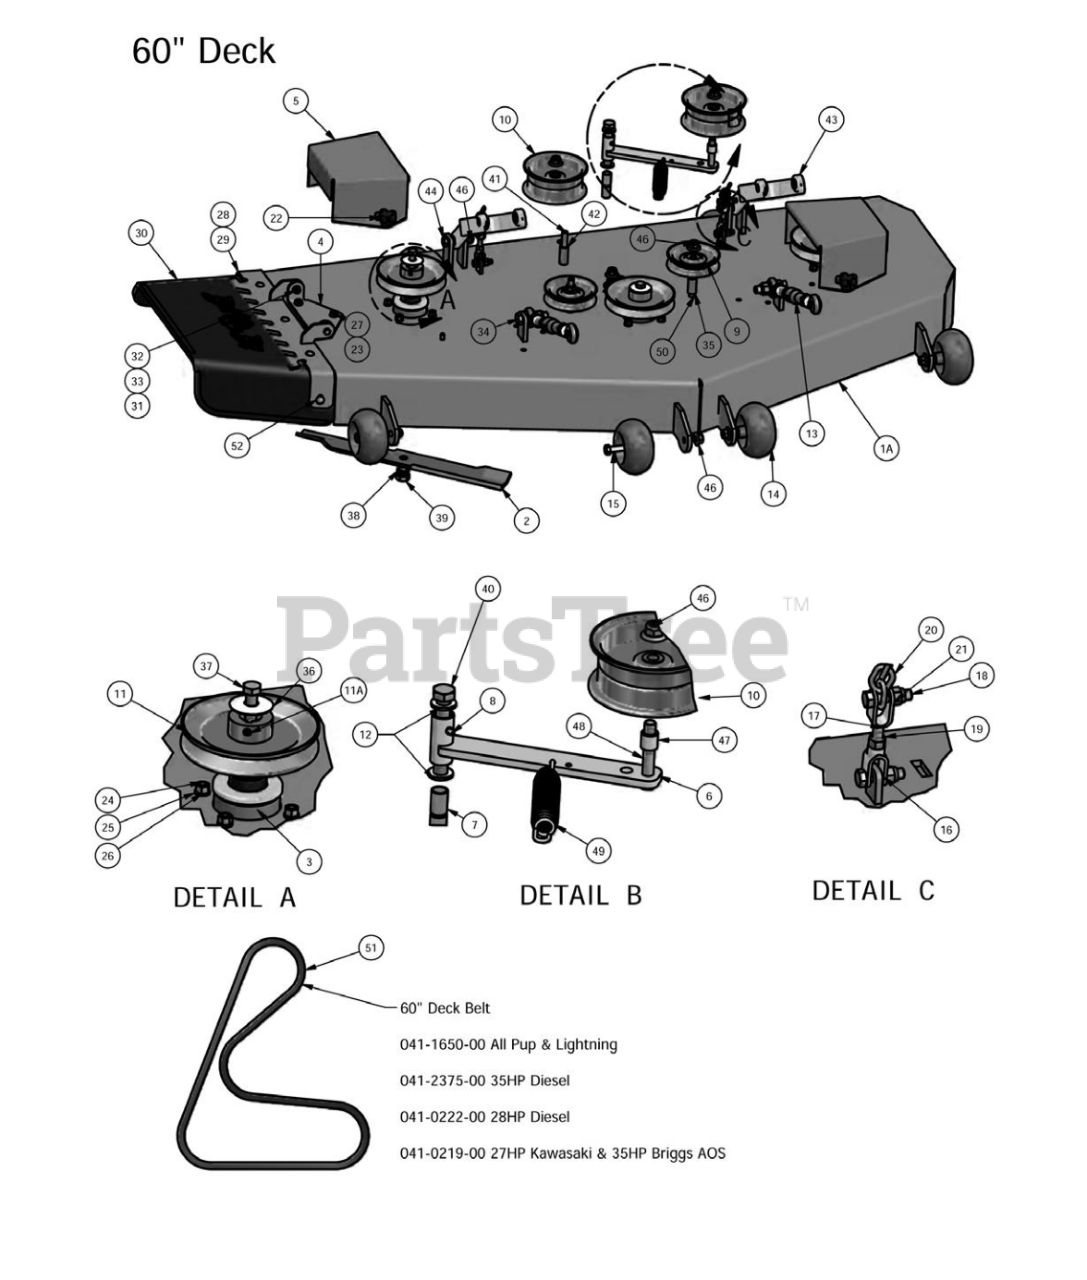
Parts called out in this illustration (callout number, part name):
1	60" Deck Complete Assembly with Spindles
1A	60" Deck Shell Only
2	60 Inch Fusion Blade
3	Double Bearing Spindle Assembly
4	Discharge Chute Hanger
5	Plastic Pulley Cover
6	Deck Idler 2009
7	5/8 x 1 1/8" Brass Bushing
8	1/4 Drive-in Grease Fitting
9	4 3/4" Idler Pulley
10	5 3/4" Deck Idler Pulley
11	6 1/4" Drive Pulley
11A	5/16" Set Screw
12	.635 ID Plastic Washer
13	Turnbuckle (Top Link)
14	Anti-Scalp Rollers
14A	Anti-Scalp Rollers Complete Assembly
15	1/2" x 4" Bolt (Grade 8)
16	Female Yoke
17A	4" Yoke & Chain Complete Assembly
17B	3" Yoke & Chain Complete Assembly
18	3/8" x 1 1/2" Hex Bolt
19	3/8" Hex Nut
20	4" Chain Assembly Lightning, AOS & Diesel
21	3/8 Nylock Nut
21A	3" Chain Assembly PUP (Only)
22	5/16" Knob
23	3/8" x 3/4" Hex Bolt
24	3/8" x 1 1/4" Hex Bolt
25	3/8" Lock Washer
26	3/8" Hex Nut
27	3/8" Flange Nut
28	60" Lower Hanger
29	60" Discharge Chute Upper Hanger Plate
30	Rubber Discharge Chute
31	.360 ID Plastic Washer
31A	Complete Assembly Rubber Discharge Chute
32	5/16" x 1" Hex Bolt
33	5/16" Nylock Flange Nut
34	5/8" x 2 1/2" Hex Bolt
35	Pup Pulley Spacer
36	Cup Washer
37	1/2" x 1 1/2" Hex Bolt
38	5/8" Lock Washer
39	5/8-18 x 1 1/2 GR 8 Hex Bolt
40	5/8" x 4" Hex Bolt
41	1/2-13 x 3 1/2 GR 5 Hex Bolt
42	1 3/4" Pulley Spacer
43	Deck Arm Assembly
44	1/2" x 2 1/2" Hex Bolt.
45	1/2" Flange Nut
46	1/2-13 Nylon Flange Nut-Orange
47	3/4 OD x 1/2 ID x 3\4 Length
48	1/2 x 3" Bolt
49	Deck Idler Spring
50	1/2 x 3 1/2 Flange Bolt Grade 8
51	Deck Belt All Pup & Lightning
51A	Deck Belt 35HP Diesel
51B	Deck Belt 28HP Diesel
51C	Deck Belt 27HP Kawasaki & 35HP Briggs AOS
52	5/16" x 1 1/4" Carriage Bolt
